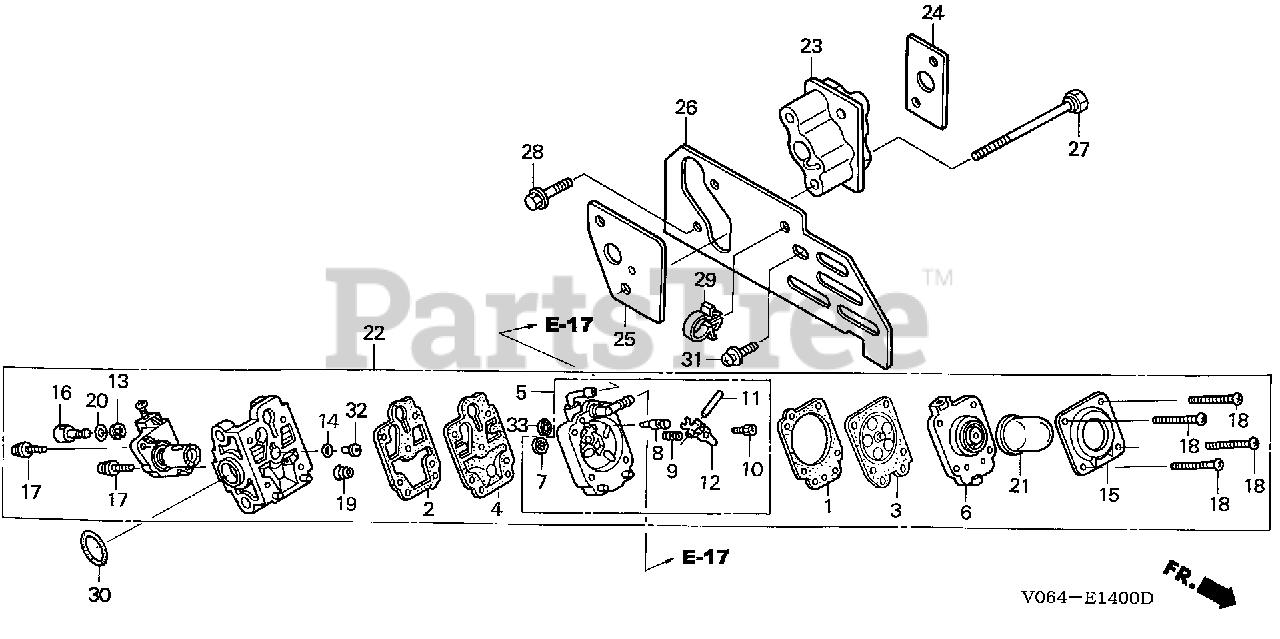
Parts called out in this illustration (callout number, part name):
1	GASKET, METERING DIAPHRAGM
2	GASKET, PUMP (CARBURETOR NO.)
3	DIAPHRAGM ASSY., METERING
4	DIAPHRAGM, PUMP
5	BODY ASSY., PUMP
5	BODY ASSY., PUMP (CARBURETOR NO.)
6	BODY ASSY., AIR PURGE
7	SCREEN, INLET (CARBURETOR NO.)
8	VALVE, INLET NEEDLE
9	SPRING, METERING LEVER
10	SCREW, METERING LEVER PIN
11	PIN, METERING LEVER
12	LEVER, METERING
13	RING, SPRING RETAINING
15	COVER, PRIMER PUMP
17	SCREW, THROTTLE COLLAR
18	SCREW, PUMP COVER
19	SPRING, PUMP
21	PUMP, PRIMER
22	CARBURETOR ASSY. (WYL 115A)
22	CARBURETOR ASSY. (WYL 99)
23	INSULATOR, CARBURETOR
24	GASKET, INSULATOR
25	GASKET, CARBURETOR
26	GUIDE, AIR INLET
26	GUIDE, AIR INLET (NOT AVAILABLE)
27	BOLT, HEX. (5X75)
28	BOLT, FLANGE (5X22)
28	BOLT, FLANGE (5X32)
29	CLIP, WIRE HARNESS
30	O-RING (14.8X2.4)
31	SCREW-WASHER (5X10)
32	JET (#38) (CARBURETOR NO.)
32	JET (#39) (CARBURETOR NO.)
32	JET (#40) (CARBURETOR NO.)
32	JET (#41) (CARBURETOR NO.)
32	JET (#42) (CARBURETOR NO.)
32	JET (#43) (CARBURETOR NO.)
32	JET (#33) (CARBURETOR NO.)
32	JET (#34) (CARBURETOR NO.)
32	JET (#35) (CARBURETOR NO.)
33	FILTER, FUEL INLET (CARBURETOR NO.)
